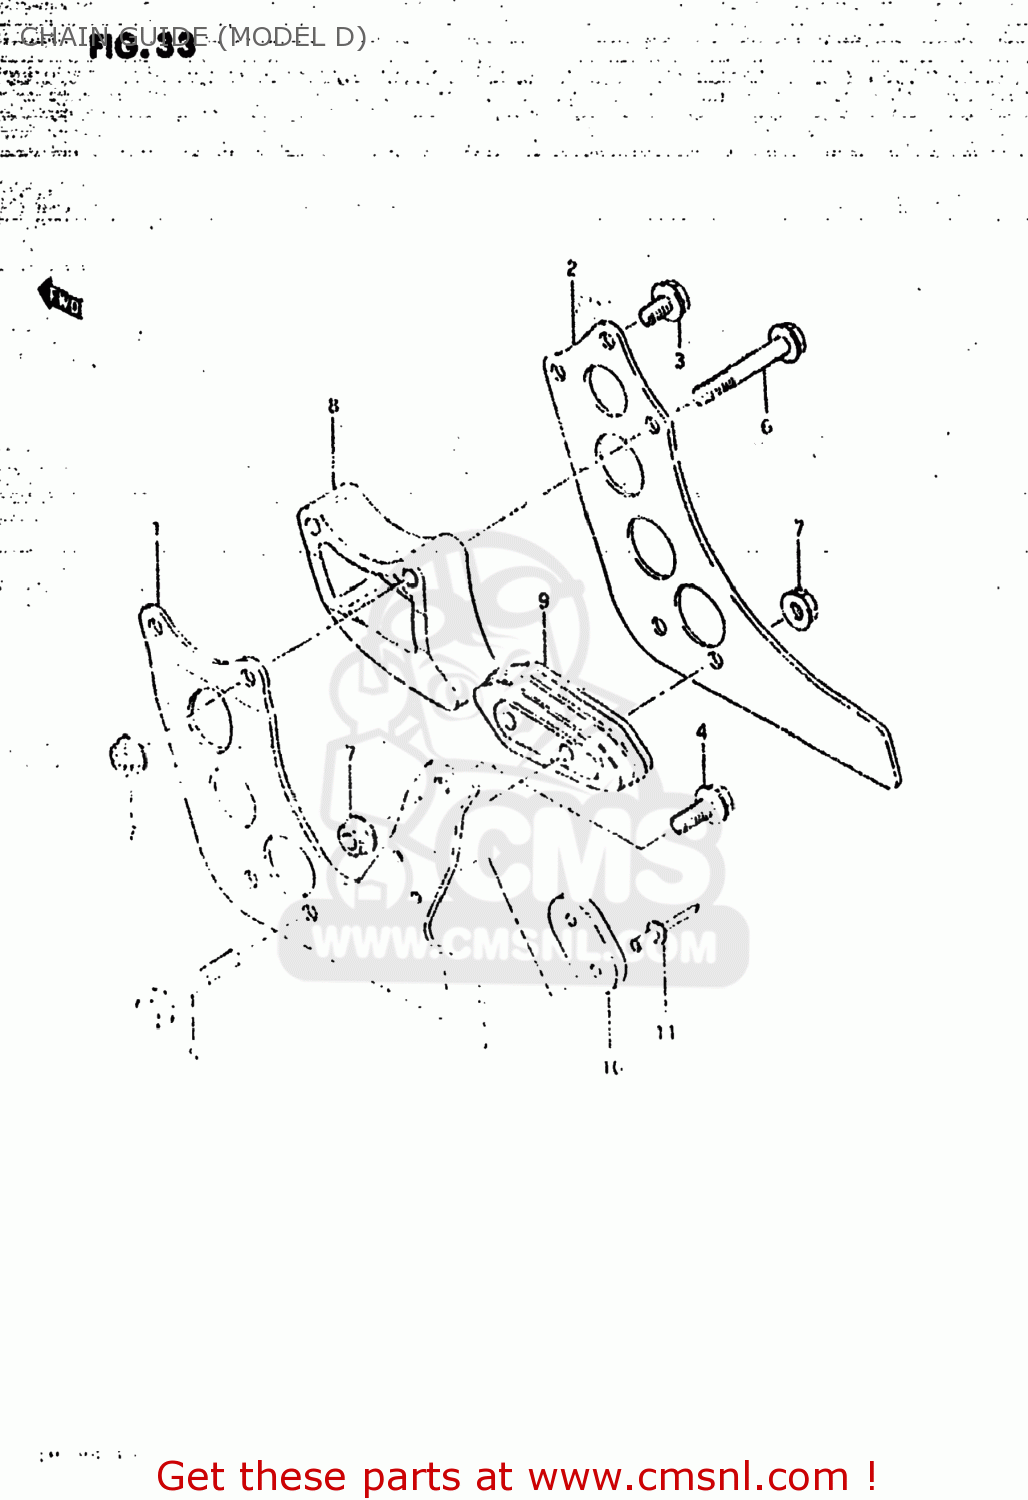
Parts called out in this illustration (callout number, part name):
1	PLATE,CHAIN GUIDE,OUTER
2	PLATE,GUIDE CHAIN
3	BOLT
4	BOLT
5	BOLT
6	BOLT,UNDER
7	NUT
8	DEFENSE,CHAIN GUIDE UPR
9	DEFENSE,CHAIN GUIDE
10	PAD,CHAIN GUIDE
11	RIVET
